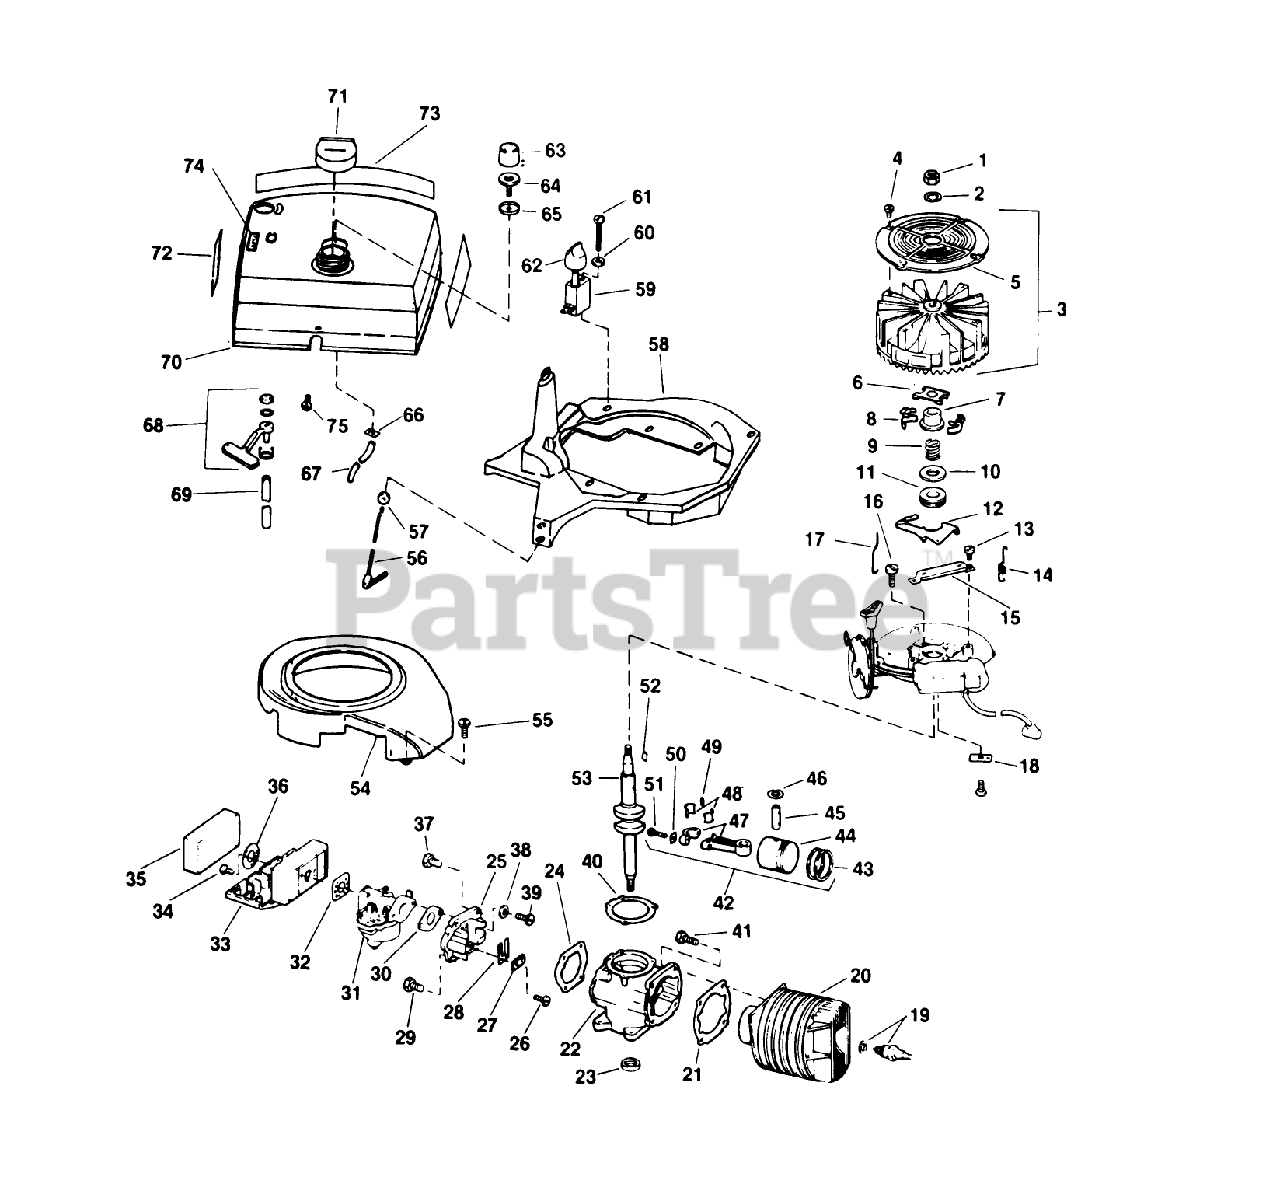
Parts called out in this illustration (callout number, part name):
1	NUT
4	SCREW F
6	YOKE S
7	COLLAR S
9	SPRING S
12	LEVER-GOVERNOR S
13	SCREW S
14	SPRING
15	BRACKET
16	SCREW S
17	ROD
18	TAB
19	Spark Plug Champion CJ-14 .035" Gap
21	GASKET S
24	GASKET S
25	REED PLATE AY. S
27	PLATE-BACKUP, REED
29	SCREW S
30	GASKET S
32	GASKET S
33	CASE
34	SCREW S
35	AIR FILTER S
36	WASHER S
37	SCREW S
40	GASKET S
44	Piston
46	RING-RETAINING
48	LINER ASM
51	SCREW
52	KEY
54	BAFFLE
55	SCREW S
57	GROMMET
60	WASHER S
65	CUP-BULB
66	LOCKNUT S
67	TUBING S
75	SCREW S
